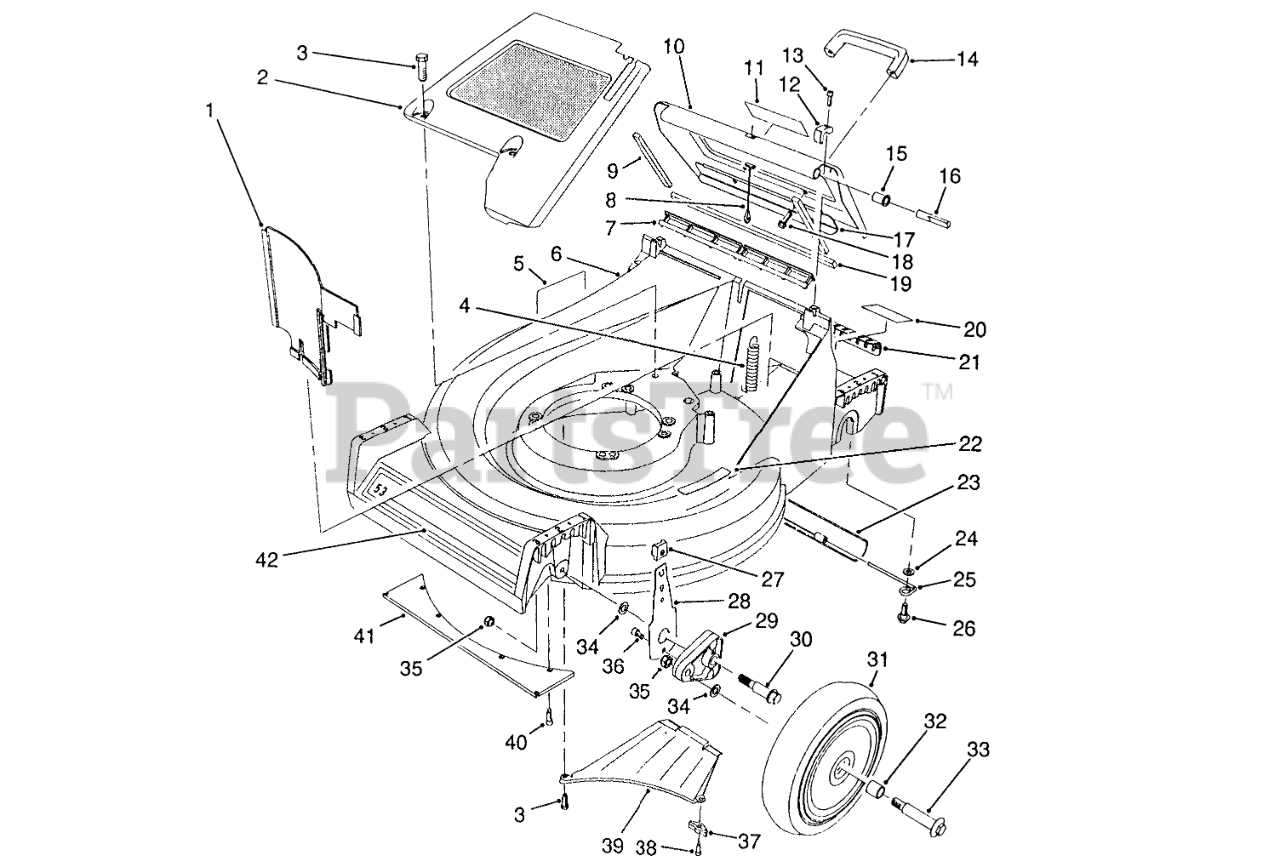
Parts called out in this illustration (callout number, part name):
1	PANEL-VERTICAL
2	PaneI-Screen
3	SCREW-HWHTF
4	EXTENSION-SPRING
5	Decal Danger
6	Housing-53cm (Incl. Ref. #5 & 22)
7	DOOR SEAL
8	DOOR CABLE
9	DOOR SIDE SEAL
10	Door-Discharge (Incl. Ref. #9. 11 & 19)
11	DECAL - DANGER
12	HINGE CLAMP
13	SCREW-HSH
14	HANDLE-DOOR
15	DOOR BUSHING
16	HINGE PIN
17	DOOR - BRACE
18	SCREW-HWH
19	DOOR END SEAL
20	Decal-Maintenance
21	ACCESS COVER
22	DECAL - STEP PAD INT'L
23	TRAILING SHIELD
24	WASHER-PLAIN
25	SHIELD HANGER
26	SCREW-SHOULDER
27	KNOB-ARM
28	FRONT SPRING ARM ASM
29	ARM-PIVOT, FRONT
30	BOLT-SHOULDER
31	Wheel & Tire Assembly (Incl. Ref. #32)
32	BUSHING
33	WHEEL BOLT
34	WASHER
35	Nut
36	SCREW-HSH, THREAD FORMING
37	Bracket-Discharge
38	SCREW-HWHTF
39	Ramp Discharge
40	SCREW-HWH
41	FRONT GUARD
42	DECAL - 53 CM
